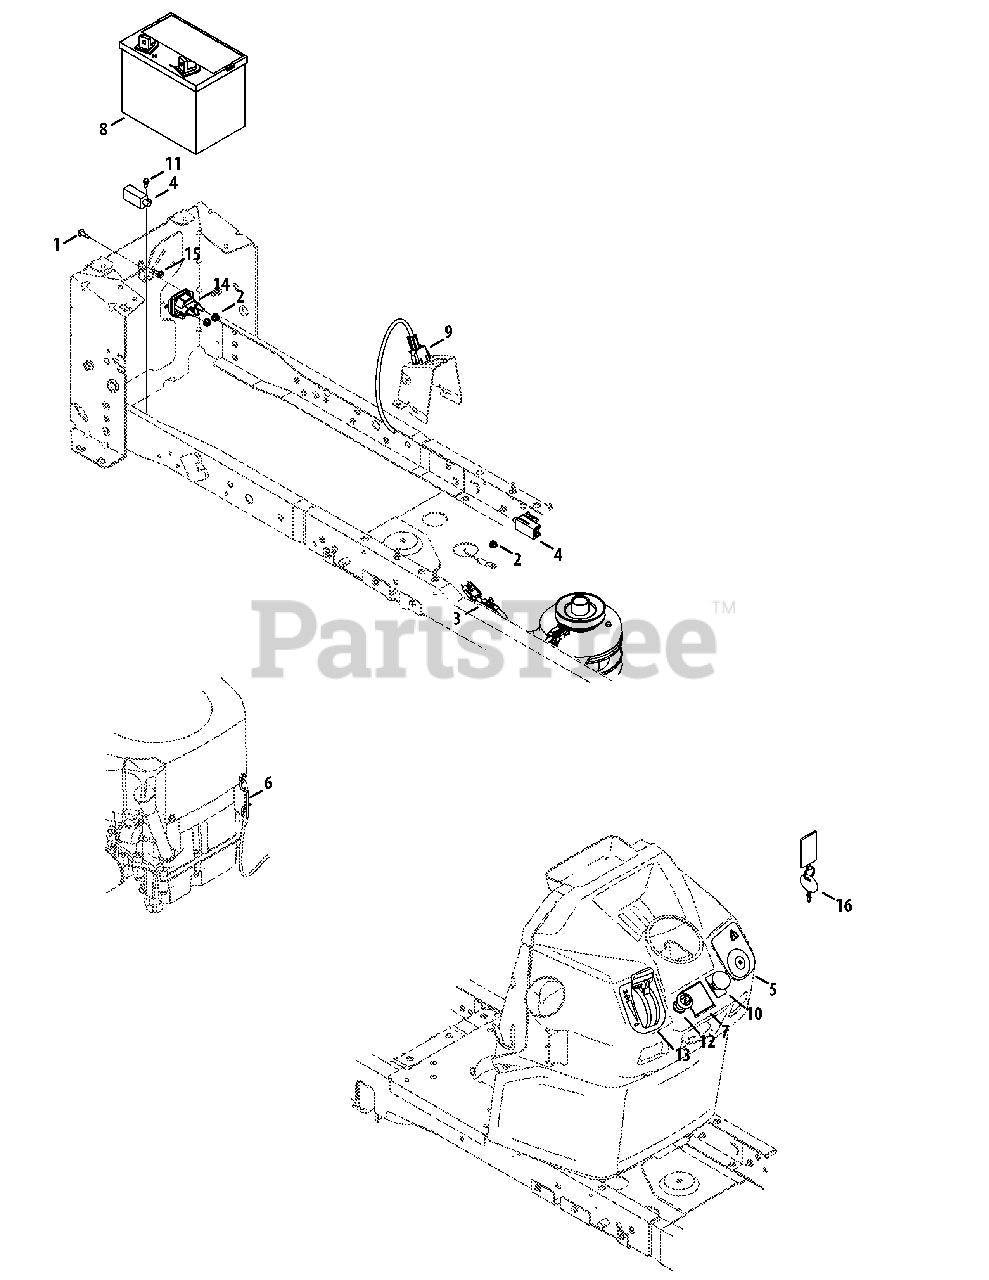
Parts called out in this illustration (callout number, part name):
1	Screw, M6-1 x .625
2	Nut, Jam Lock, 1/4-20, Nylon
3	Jumper Harness
4	Switch, Interlock
5	Key Switch
6	Cable Guide Rod
7	Hour Meter
8	Battery
9	Dash Harness
10	PTO Switch
11	Shoulder Screw, #10-32 x .500
12	Choke Plug
13	Throt/Choke Cable, 43.5"
14	Solenoid
15	Self-tapping Screw, 1/4-20 x .625
16	Key, Assembly
